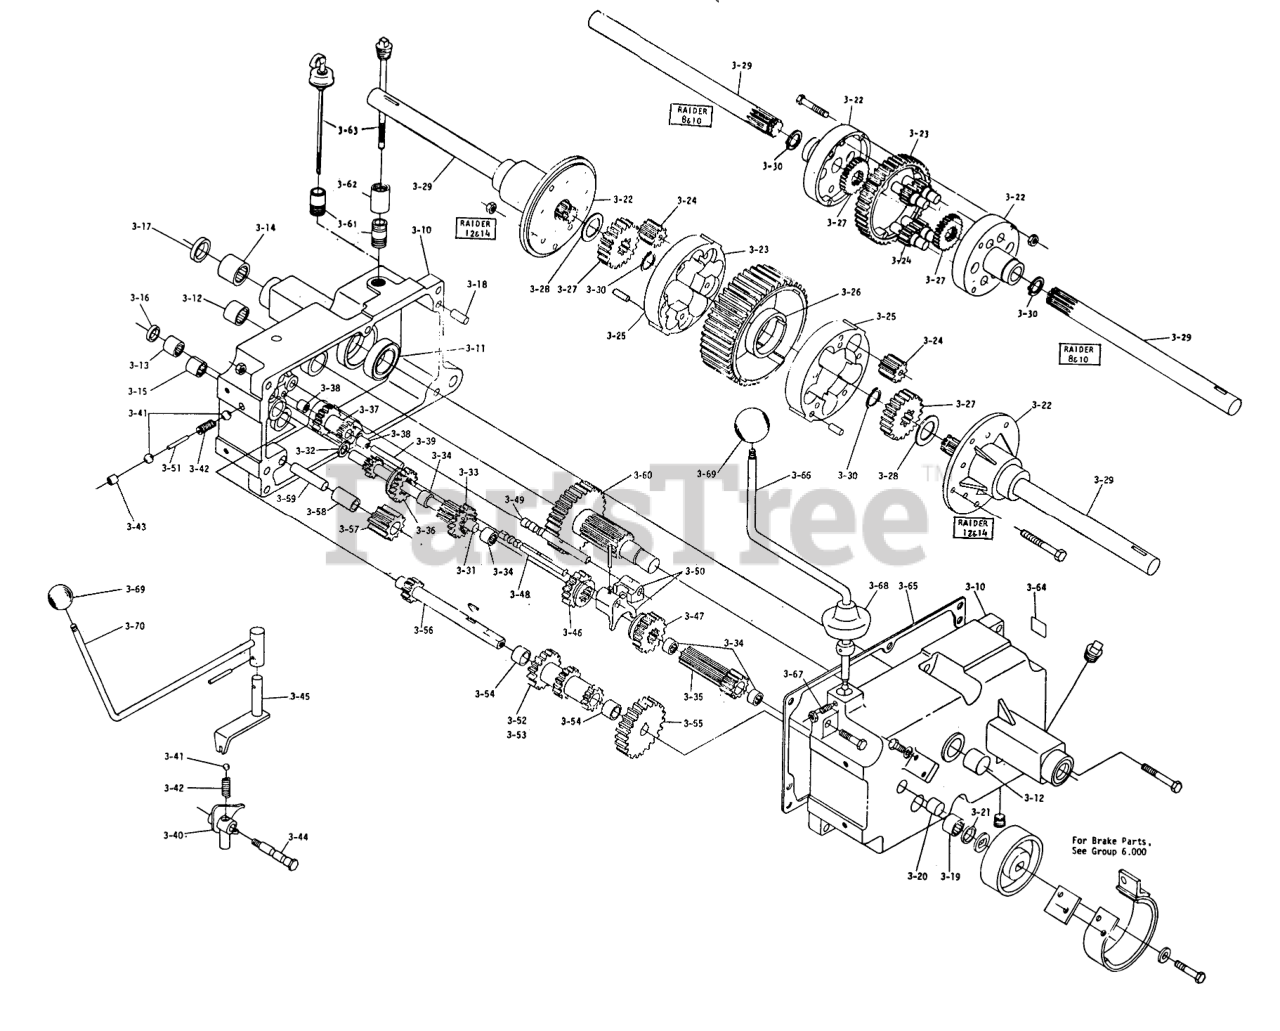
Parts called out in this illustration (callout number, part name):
3-10	Case-R.H.
3-10	Case LH.
3-10	Bolt Hex 3/8-16 x 1
3-10	Bolt, 3/8 16 x 2
3-10	PLUG 1/4 PIPE ALLEN
3-10	Plug
3-10	Case RH
3-10	Case L.H.
3-11	BALL BRG 1 1/2 I.D.
3-12	BEARING-NEEDLE
3-13	BEARING-NEEDLE
3-14	BEARING-NEEDLE
3-14	Bearing-Axle
3-15	BEARING-NEEDLE
3-16	SEAL-OIL
3-17	OIL SEAL
3-17	SEAL-OIL
3-18	PIN-DOWEL
3-19	BEARING-NEEDLE
3-20	Bearing Needle
3-21	SEAL-OIL
3-22	Case-Differential
3-22	Bolt, 5/16-18 x 1/4
3-22	Nut 5/16-18
3-22	End Cap-RH
3-22	End Cap-LH
3-22	Bolt Hex 3 1/4
3-22	3/8-16 E.S.
3-23	Bull Gear
3-23	Gear-Ring
3-24	GEAR-PINION, 11T
3-24	PINION
3-25	Body
3-25	SPIROL ROLL PIN
3-26	Spring
3-27	AXLE GEAR
3-27	SIDE GEAR
3-28	THRUST WASHER
3-29	Axle, R.H.
3-29	Axle, L.H.
3-30	Snap Ring
3-30	SNAP RING
3-31	SHAFT-INPUT
3-32	WASHER-THR
3-33	GEAR
3-34	BEARING-NEEDLE
3-35	GEAR
3-36	GEAR-SLIDING
3-37	Gear
3-38	BEARING-NEEDLE
3-39	GEAR-SHAFT REDUCTION
3-40	Shift Fork
3-41	BALL-DETENT
3-42	Spring
3-43	CUP-PLUG
3-44	BOLT-DETENT
3-45	SHIFT ASM
3-46	GEAR-HI AND 2ND
3-47	GEAR-LOW AND REVERSE
3-48	RAIL-SHIFT
3-49	RAIL-REAR SHIFT
3-50	FORK-SHIFT
3-50	PIN-ROLL
3-51	PIN-SHIFT
3-52	GEAR-CLUSTER
3-53	Cluster Gear
3-54	BUSHING-BRONZE
3-55	GEAR-CLUSTER SHAFT
3-56	Cluster Shaft
3-56	Key
3-57	GEAR/BUSHING ASM-REVERSE IDLER
3-58	BUSHING
3-59	PIN-DIFFERENTIAL
3-60	Gear 44T-11T
3-61	Nipple-1/2" X 1 1/2" Pipe
3-63	Dipstick
3-65	GASKET-TRANSMISSION
3-66	Shift Stick
3-67	SETSCREW
3-67	Nut 1/4-20
3-68	COVER-DUST
3-69	Knob
3-70	Handle-Shift
3-70	PIN-SPIROL
